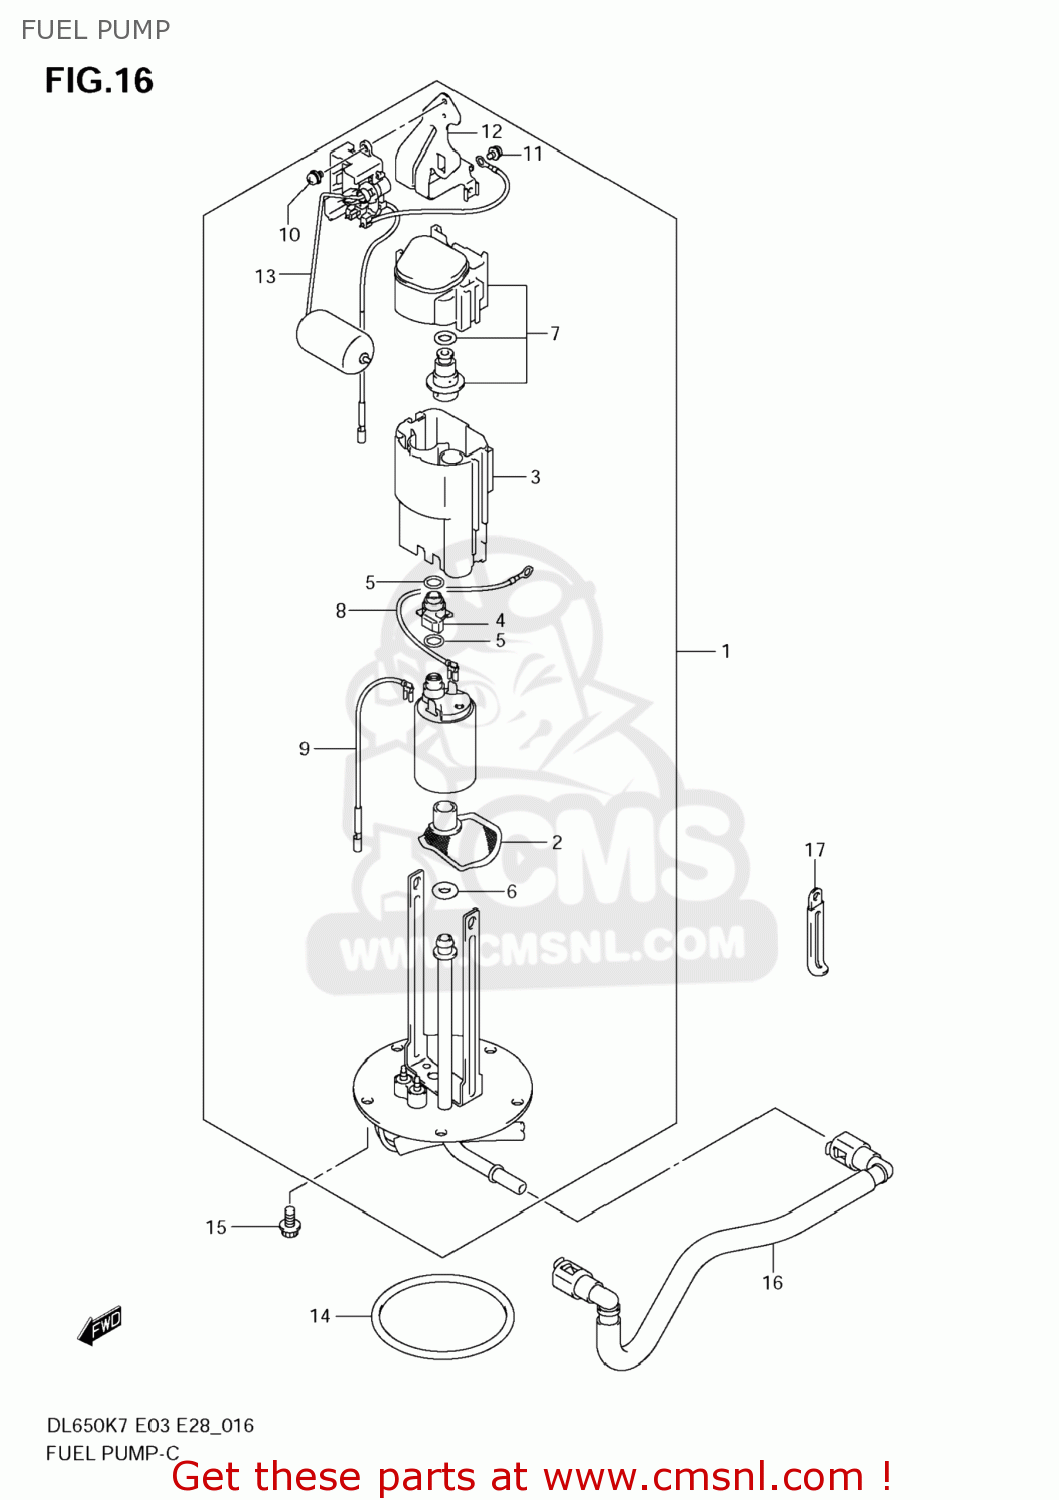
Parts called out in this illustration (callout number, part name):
1	PUMP ASSY,FUEL
2	STRAINER
3	CUP
4	JOINT
5	O RING
6	O RING
7	REGULATOR
8	WIRE,EARTH
9	WIRE,LEAD
10	SCREW
11	SCREW
12	BRACKET,GAUGE
13	GAUGE ASSY,FUEL LEVEL SENDER
14	O RING,FUEL PUMP
15	BOLT
16	HOSE COMP,FUEL
17	CLAMP(L:45)
